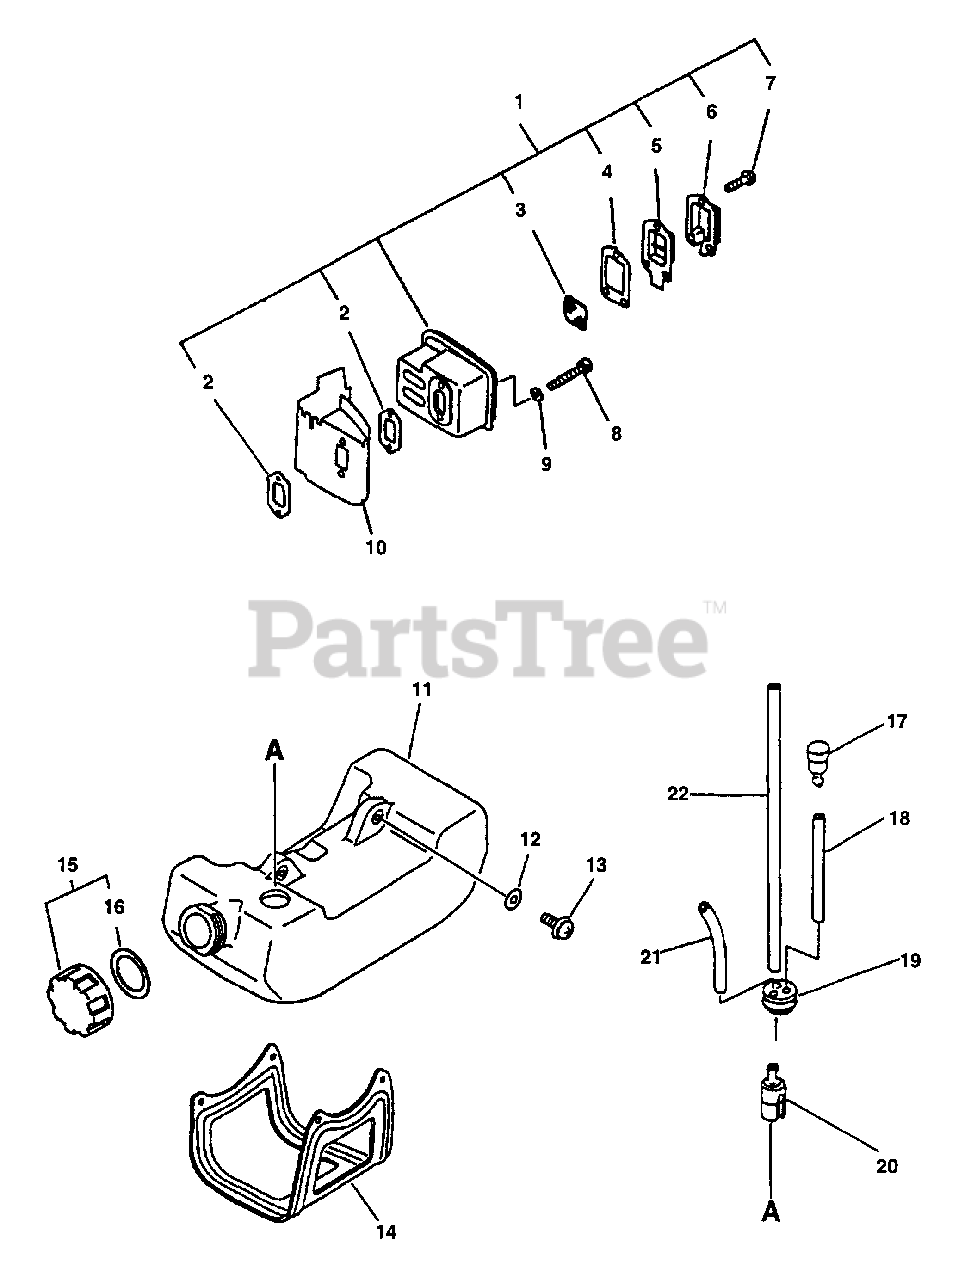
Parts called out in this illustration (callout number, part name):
1	MUFFLER ASSY
2	GASKET, EXHAUST
3	SCREEN, SPARK ARRESTER
4	GASKET, EXHAUST
5	GUIDE, EXHAUST
6	OUTLET, EXHAUST
7	SCREW 4×10
8	BOLT 5×55
9	WASHER, FLAT 5.5×10×0.8
10	COVER, EXHAUST
11	TANK, FUEL
12	WASHER 5.5×12×0.8
13	SCREW 5×16
14	GUARD, FUEL TANK
15	CAP ASSY, FUEL
16	GASKET, FUEL CAP
17	VENT ASSY
18	PIPE, FUEL 3x-5x-70 BLACK
19	GROMMET, FUEL
20	FILTER, FUEL
21	PIPE, FUEL 3×6×80 CLEAR
22	PIPE, FUEL 3x-5x-180
